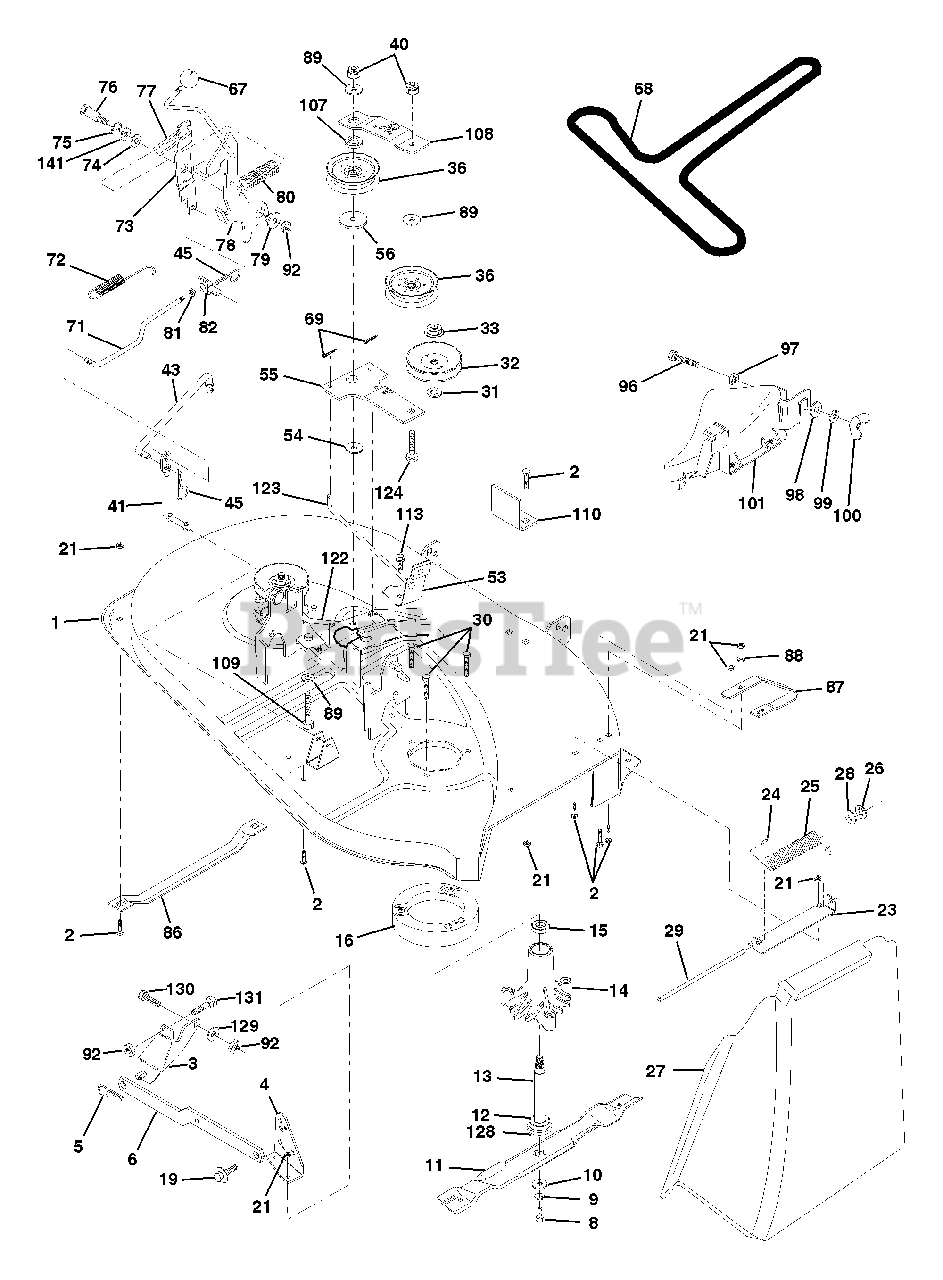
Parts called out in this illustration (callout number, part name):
1	Deck Asm Weldment
2	Bolt Rdhd Sqnk 5/16-18 unc X 3/4
3	Bracket Asm Fr Sway Bar 38/42
4	Bracket Asm Deck Sway Bar
5	Retainer Spring
6	Arm Suspension Rear
8	Bolt 3/8 - 24 X 1.25 Gr 8
9	Washer Lock Hvy 3/8
10	Washer Hard Blade Mower Vented
11	Blade Mower Mulching 38"
12	Bearing Ball #6024 (Mandrel)
13	Shaft Asm W/lower Bearing
14	Housing Mandrel Vented
15	Bearing Ball Mandrel
16	Stripper Mower Vented
19	Bolt Shoulder
21	Nut Crownlock 5/16-18 UNC
23	Bracket Deflector Mower
24	Cap Sleeve 80 x 112 Blk Mower
25	Spring Torsion Deflector 2 52
26	Nut Push Phos & Oil
27	Shield Deflector
28	Washer 11/32 X 5/8 X 16 Ga
30	Screw Thdrol Rolling Washer Head
31	Washer Spacer Mower Vented
32	Pulley Mandrel
33	Nut 9/16 Toplock Flng Oil Dip
36	Pulley Idler Flat 3 060
40	Nut Crownlock 3/8-16 UNC
41	Rod Pivot W/nibs
43	Rod Clutch Secondary
45	Spring Retainer 1" Zinc/cad
54	Washer Hardened
56	Spacer Retainer Pm Mower
67	Knob Rd 7/16-14 Plstc Thds Blk
68	V-Belt Mower
69	Pin, Cotter 3/32 x 3/4
71	Rod Clutch Primary 38/42
72	Spring Return
73	Arm Clutch Secondary
74	Washer 25/32 X 1-5/8 X 16 Ga
75	Ring Klip #t5304-75
76	Bolt Shoulder 3/8-16 Unc 1 44
77	Keeper Spring 4 000
78	Arm Asm Clutch Primary
79	Bushing 747 Od X 794 Lg Brass
80	Spring Clutch Mower
81	Nut Hex Jam 3/8-16
82	Trunnion Adj 94
86	Runner, LH
87	Runner, RH
88	Washer 11/32 x 3/4 x 16 Ga.
89	Washer 13/32 x 1 x 12 Ga.
92	Nut Lock Hex W/Ins 3/8-16 Unc
96	Bolt 3/8-16 x 1-1/4 Mulcher
97	Nut Crownlock 3/8-16 UNC
98	Washer 13/32 x 1-1/4 x 16 Ga.
99	Washer Lock Hvy Hlcl Spr 3/8
101	Cover Asm Mulching 38"
107	Spacer, Retainer
108	Stiffener, Idler Arm
109	Bolt, Hex Head 3/8-16 x 2-1/2
110	Upstop Deck Front 38"
113	Screw Thdrol 5/16-18 X 3/4
122	Rod, Brake, LH
123	Rod, Brake, RH
124	Bolt, Carriage 3/8-16 x 1-3/4
128	Washer Felt
129	Washer 13/32 x 13/16 x 12 Ga.
130	Bolt, Fin Hex 3/8-16 UNC x 1 Gr. 5
131	Bolt, Rdhd Sqnk 3/8-16 x 1
141	Washer Thrust .75 x 1.230
